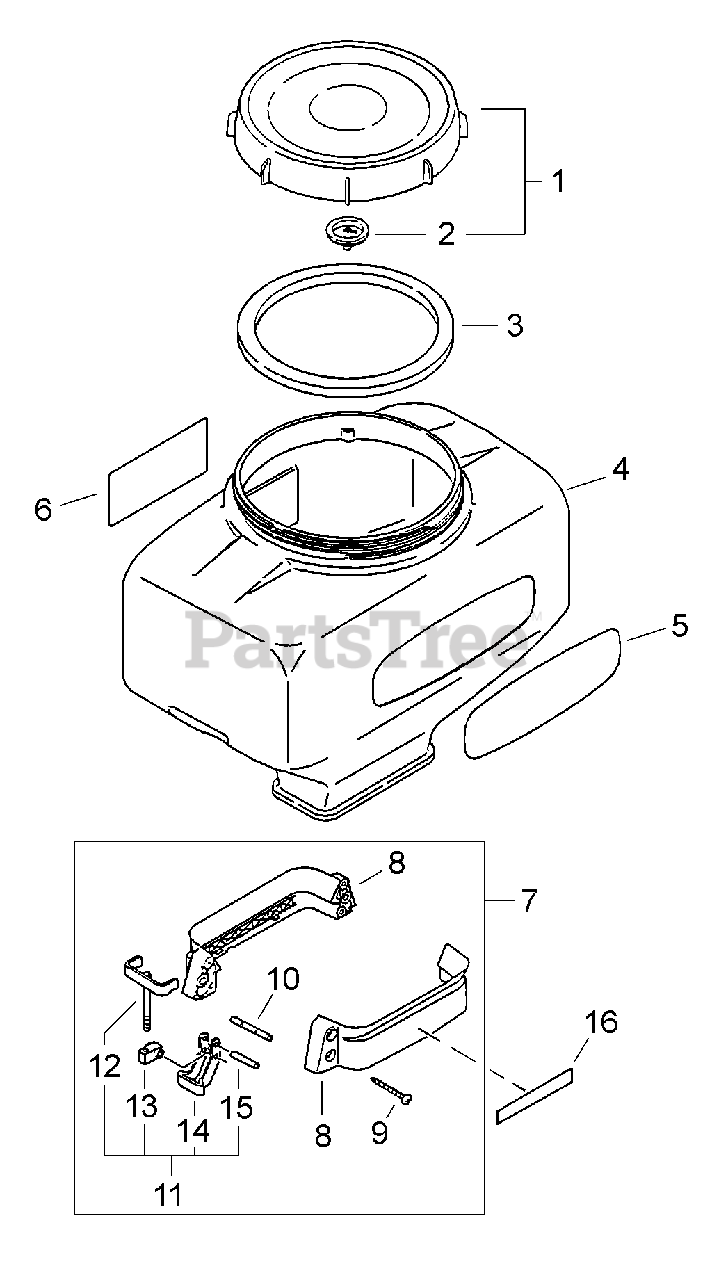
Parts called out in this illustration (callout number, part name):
1	CAP, CHEMICAL TANK
2	VENT, TANK
3	GASKET, CAP
4	TANK, CHEMICAL - 23 LITER
5	LABEL - ECHO
6	LABEL - CAUTION
7	BRACKET ASSY
9	SCREW - 5X35
11	CLAMP ASSY
13	CONNECTOR
14	BRACKET, TANK
15	PIN
16	LABEL - MODEL DM-4610
